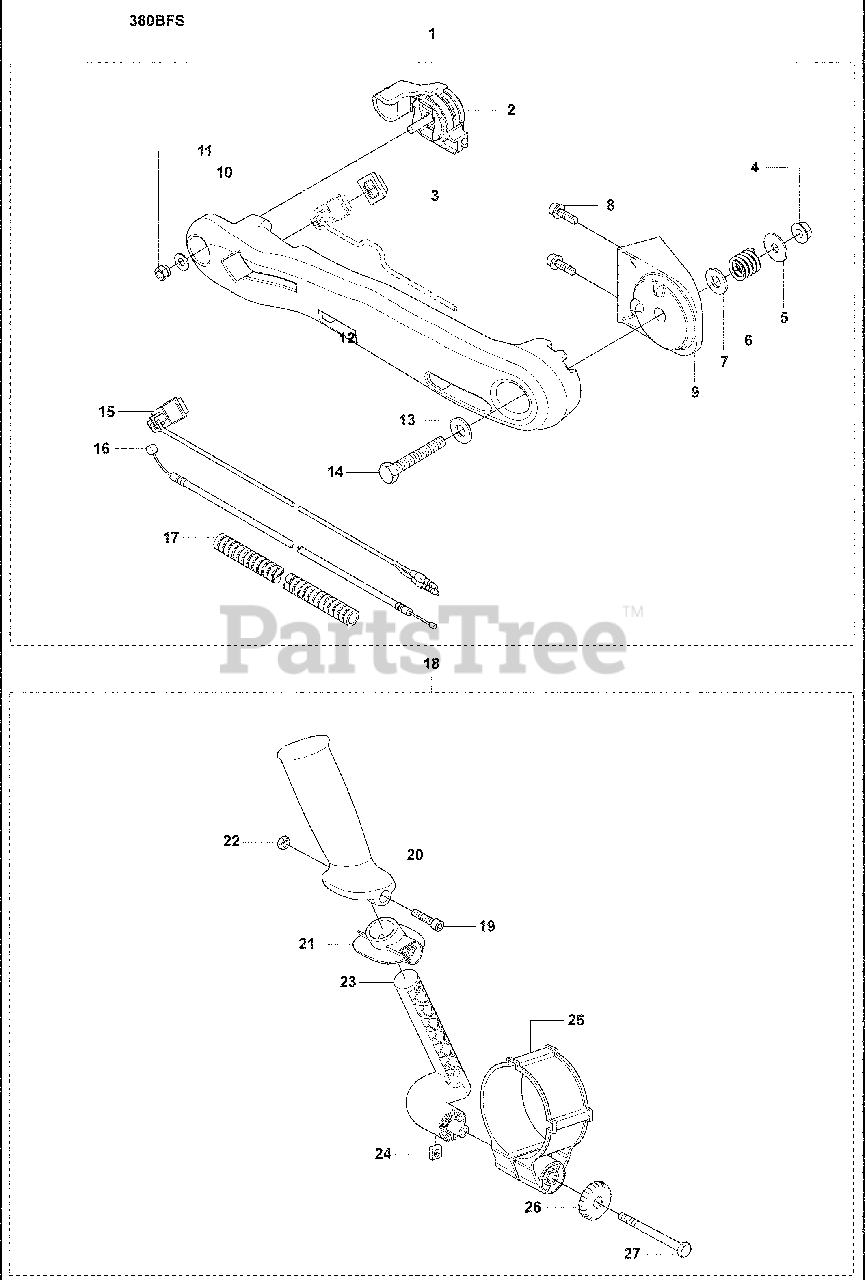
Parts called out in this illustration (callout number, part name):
1	Handle Assembly
2	Lever
3	Switch Cap
4	Nut
5	Washer
6	Spring
7	Washer
8	Screw
9	Bracket
11	Nut
12	ARM
13	Washer
14	Bolt
16	Cable, Complete
19	Screw
22	Hex Nut, M5 X .80 DIN
23	Holder
24	Square Nut
25	HOLDER TH
26	Air Filter Cover Knob
